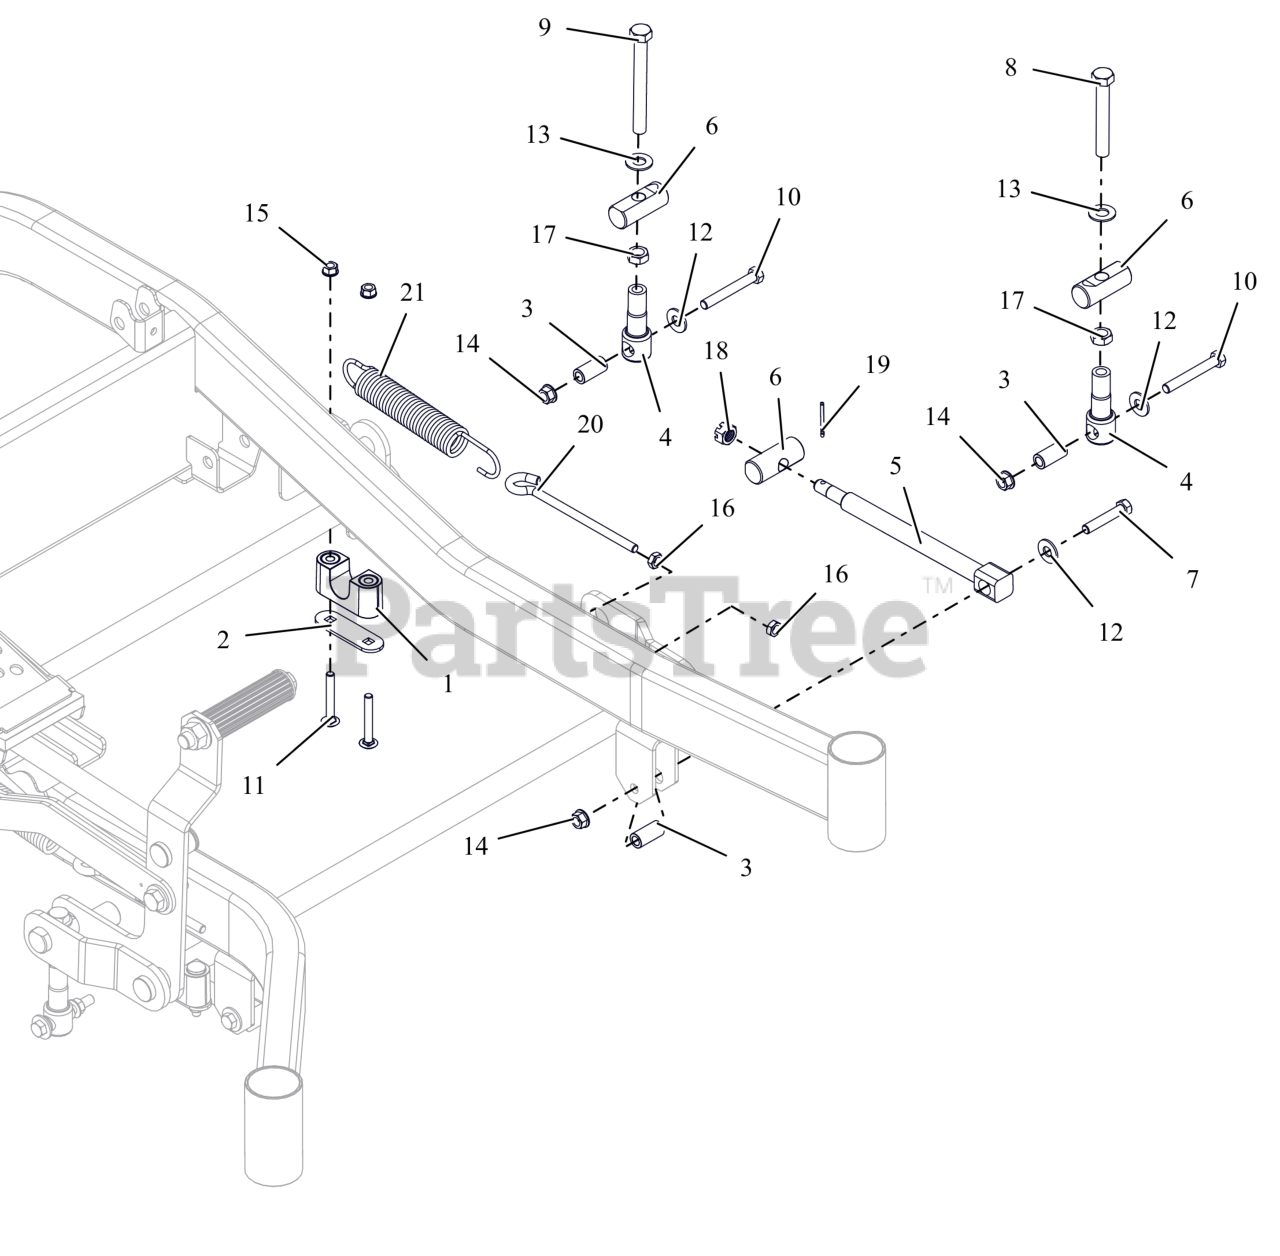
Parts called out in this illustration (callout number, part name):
1	ASM-BUSHING, DECK LIFT
2	PLATE, BEARING SUPPORT
3	SPACER, DECK LEVELING
4	LINK, DECK LIFT FORMED
5	DRAG,LINK-HD
6	PIN, DECK LIFT
7	BLT,HEX .38-16X2.00 G5 ZCC
8	BLT, HEX .50-13X3.50F G5 ZCC
9	BLT, HEX .50-13X4.50F G8 ZCC
10	BLT, HEX .38-16X2.75 G8 ZCC
11	BLT, RHSSN.31-18X2.25 G5 ZCC
12	WSHR,FLT .438X1.00X.083 ZCC
13	WSHR, FLT .557X1.040X.102 ZCC
14	NUT-LK-TOP-FLG .38-16 ZC120
15	NUT,LK-CTR-FLG .31-18 GF ZCC
16	NUT-JAM .375-16 G2 ZCC
17	NUT-JAM .500-13 G2 ZCC
18	NUT-SL .50-13
19	PIN,CTR.12X1.25EXTPRSQCT ZC120
20	BOLT,.38-16 X 5.25-.62 DIA EYE
21	SG-TENS .162X1.25X8.25 WLD 25
